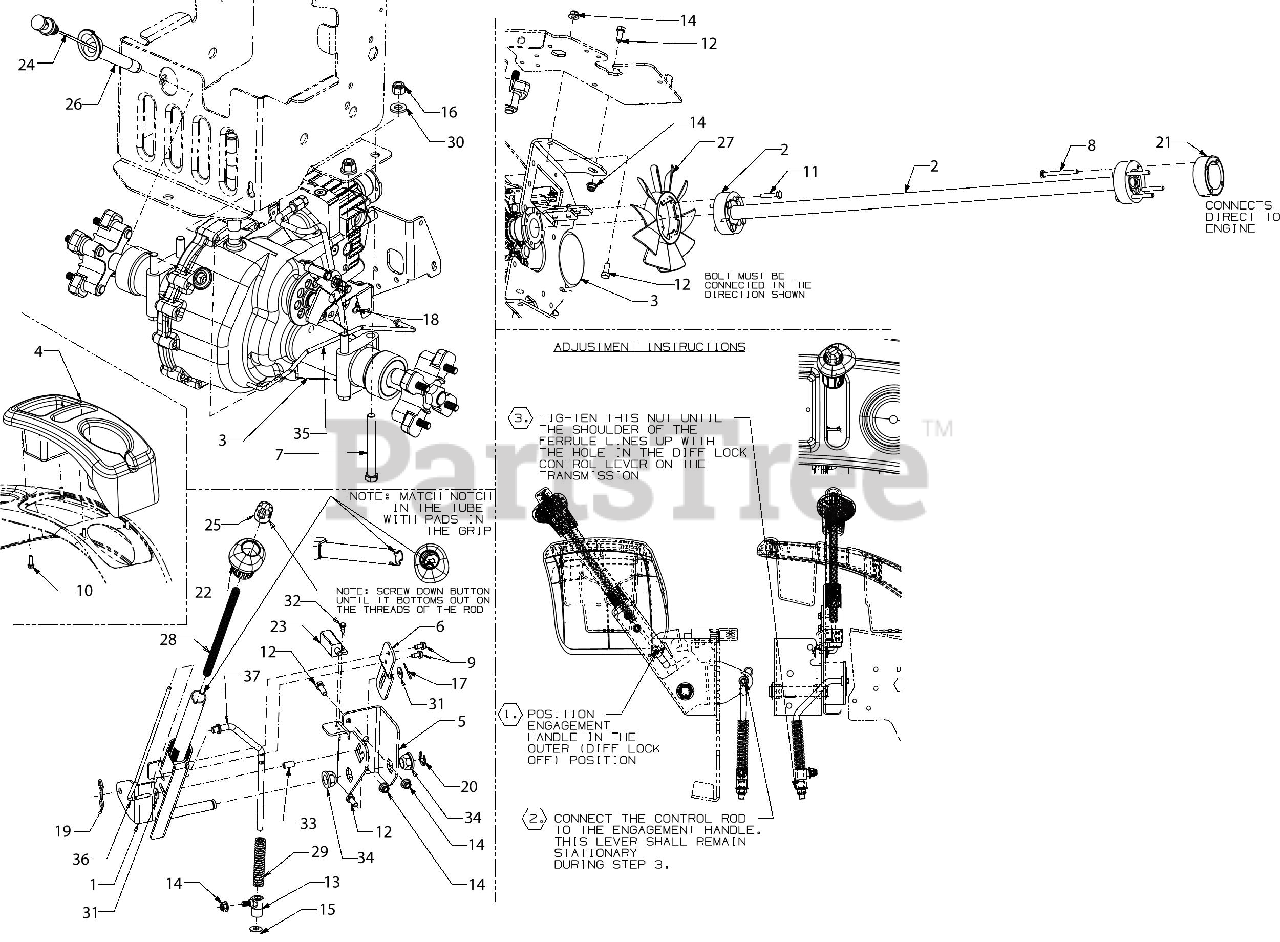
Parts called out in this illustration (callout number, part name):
1	DIFF LOCK ENGAGE HANDLE ASSEMBLY
2	DRIVE SHAFT ASSEMBLY 30.55
3	SERVICE TRANSMISSION (W/O HUBS & PUMP)
4	CVR-CUP/DIF LOC FNDR (LH)
5	HANDLE MOUNTING BRACKET
6	DIFF LOCK BRACKET
7	SCREW 1/2-20 x 4.50 GR5
8	SCREW 1/4-20 x 2.50 GR5
9	SCREW 1/4-20 X.500
10	SCREW 1/4-15 x .750
11	SCREW 1/4-20 x 1.25 GR5
12	SCREW 5/16-18 x .75 GR5
13	SHOULDER FERRULE 3/8 ID x .420
14	FLANGE LOCK NUT 5/16-18
16	HEX NUT CENTER
17	COTTER PIN-3/32
18	BOW TIE COTTER PIN 1/4-5/16
19	PIN:COTTER
21	DRIVE SHAFT ADAPTER
23	INTERLOCK SWITCH (NO/NC)
24	TRANSMISSION DIPSTICK
25	DIFF LOCK HANDLE BUTTON
26	DIPSTICK HOLDER
27	10 BLADE COOLING FAN
28	COMPRESSION SPRING .400 x 9.52 GSX
29	COMPRESSION SPRING .676 OD x 3.215 LG
30	FLAT WASHER .531X1.060X.134
31	FLAT WASHER
32	SHOULDER SCREW
33	SLEEVE SPACER .24X.37X.685
34	FLANGE BEARING
35	HYDRO PUMP RELEASE ROD
36	DIFF LOCK BUTTON ROD
37	DIFF LOCK ENGAGEMENT ROD
